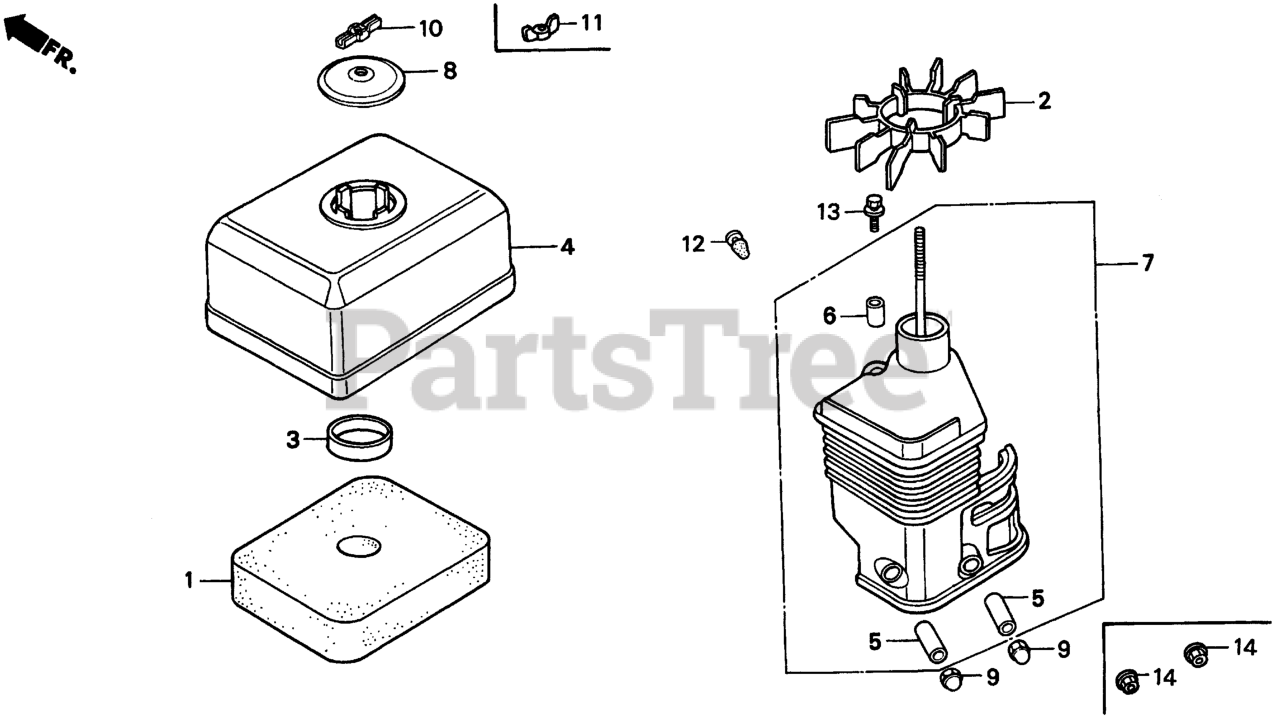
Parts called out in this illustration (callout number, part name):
1	ELEMENT, AIR CLEANER (DRY)
2	HOLDER, ELEMENT
3	COLLAR, HOLDER
4	COVER, AIR CLEANER (SEMI-DRY)
5	COLLAR, AIR CLEANER Use from Engine SN 1786085.
6	COLLAR B, AIR CLEANER
7	ELBOW, AIR CLEANER
8	CAP, AIR CLEANER
11	WINGNUT, TOOL BOX SETTING
12	PLUG, CONE TYPE
13	BOLT, FLANGE (6X20)
14	NUT, FLANGE (6MM)
